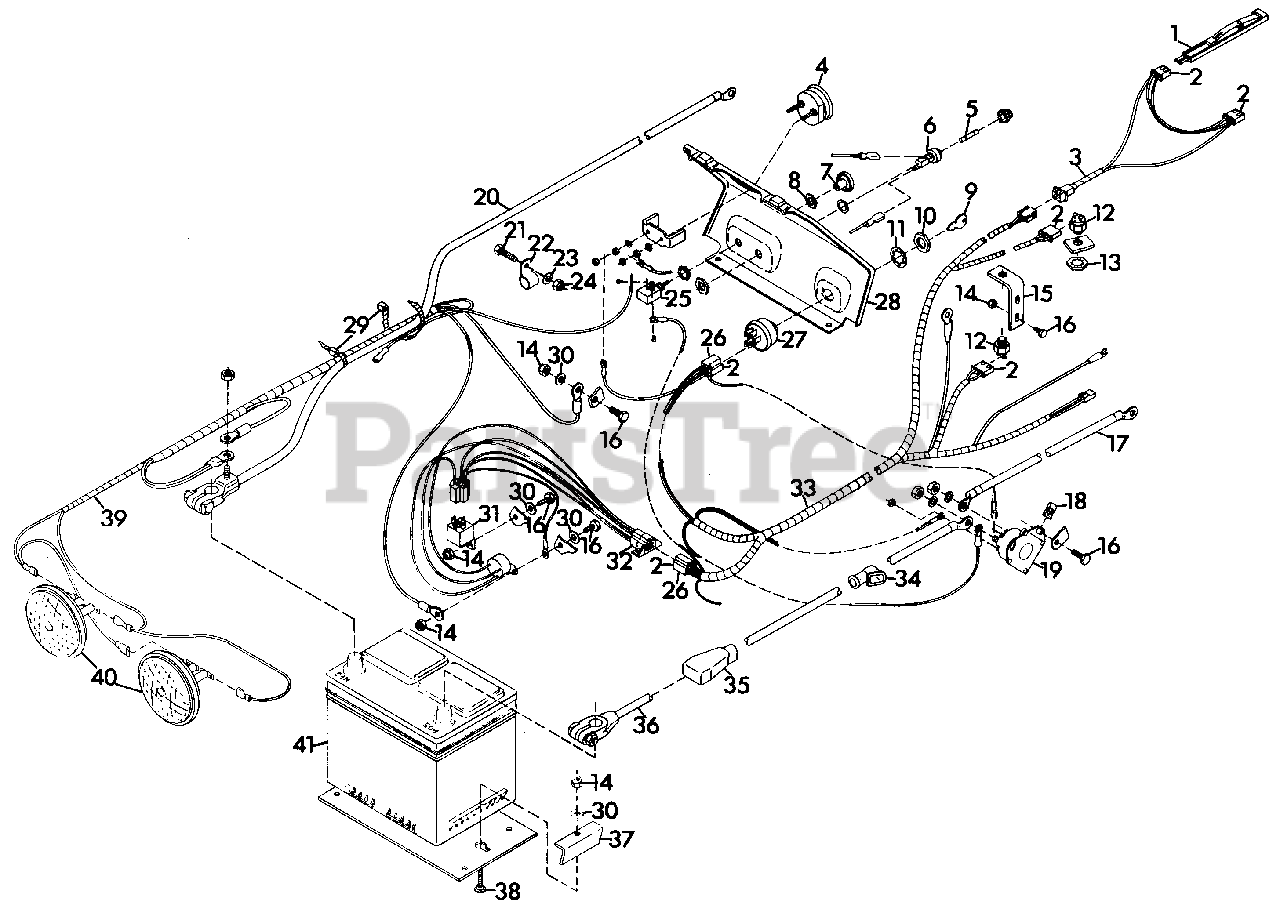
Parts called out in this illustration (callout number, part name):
1	SWITCH, SEAT
2	TERMINAL
3	HARNESS, WIRING SEAT SWITCH
4	GAUGE, AMMETER
5	FUSE, 30 AMP AGC 30
6	FUSE, PANEL
7	KNOB, LIGHT SWITCH
8	NUT, SPECIAL LIGHT SWITCH
9	KEY, IGNITION SWITCH
10	NUT, JAM 9/16-24
11	WASHER, LOCK INT. TOOTH
12	SWITCH, INTERLOCK
13	NUT, STAMPED 9/16-18
14	NUT, LOCK 1/4-20
15	BRACKET, SWITCH
16	BOLT, HEX 1/4-20X.75
17	CABLE, STARTER
18	NUT, SPEED 1/4-20
19	SWITCH, MAGNETIC
20	CABLE, NEGATIVE BATTERY
21	BOLT, HEX 5/16-18X1.00
22	CLAMP, NYLON
23	WASHER, FLAT .344X.688X.065
24	NUT, LOCK 5/16-18
25	SWITCH, LIGHT
26	CONNECTOR
27	SWITCH, IGNITION
28	PANEL, INSTRUMENT
29	TIE, CABLE
30	WASHER, FLAT .281X.625X.065
31	RELAY
32	MODULE, TIME DELAY
33	HARNESS, WIRING B&S
34	BOOT, BATTERY CABLE
35	COVER, BATTERY TERMINAL
36	CABLE, BATTERY TO MAGNETIC SWITCH
37	CLAMP
38	BOLT, 1/4-20X1.75 RD HD SQ NK
39	HARNESS, WIRING GROUND AND LIGHTS
40	HEADLIGHT
41	BATTERY, 12 VOLT
